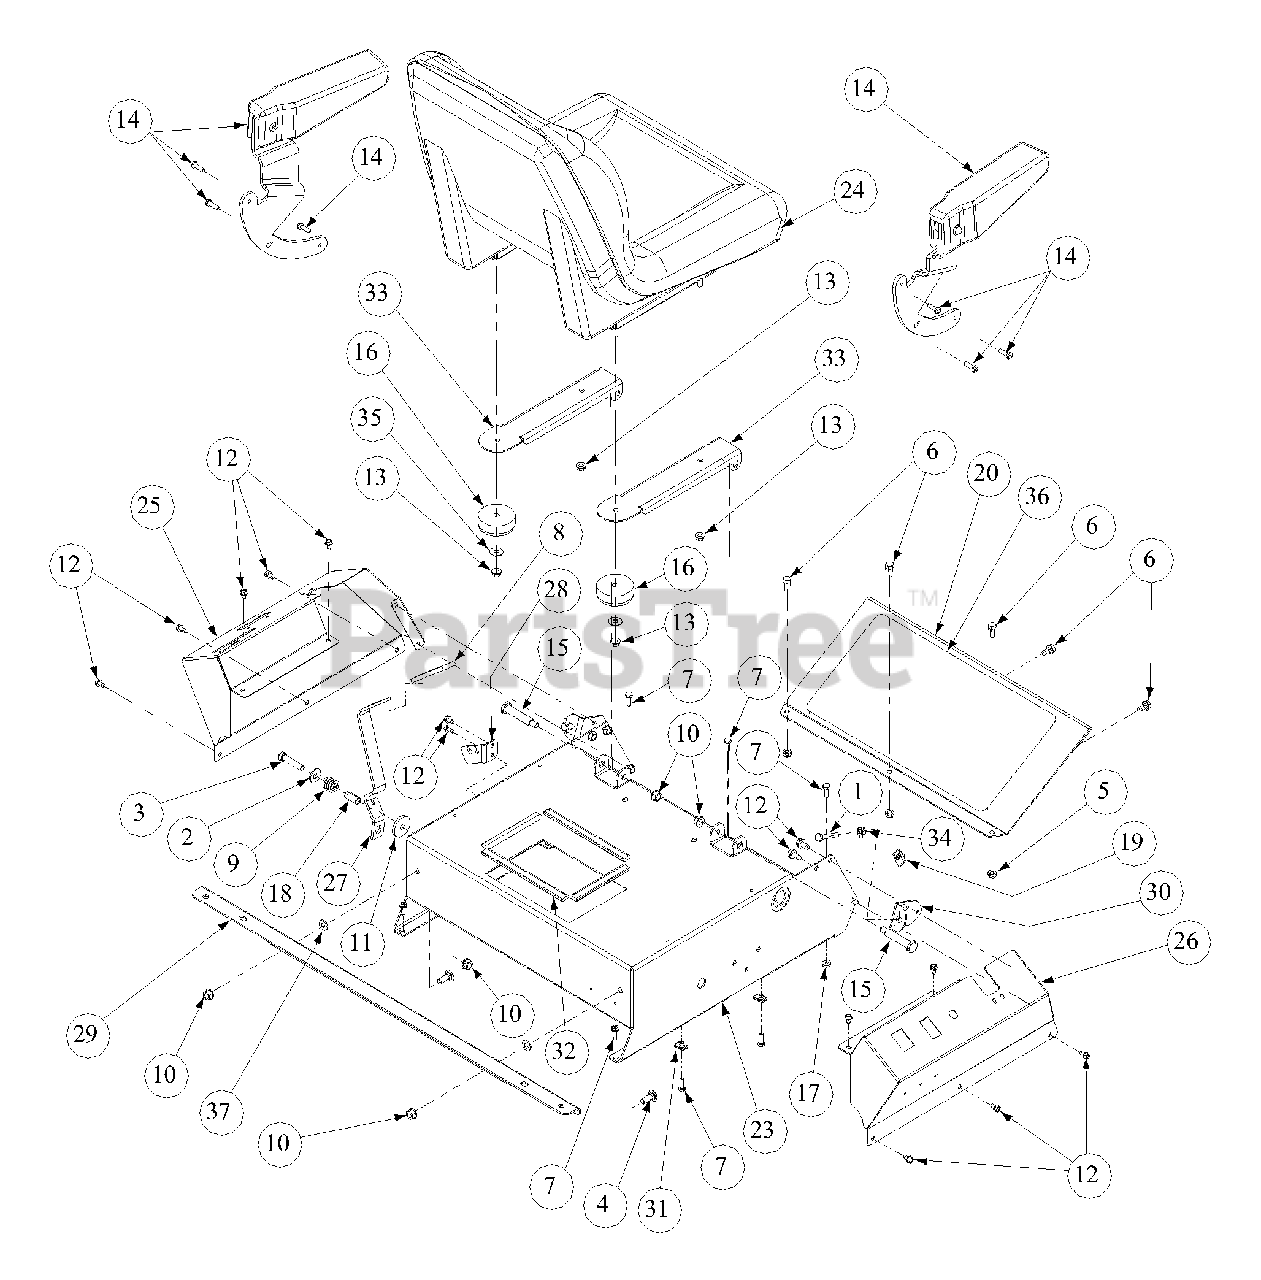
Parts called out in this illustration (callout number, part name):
1	Hex Cap Screw, 5/16-18 x 1-1/2
2	Idler Washer
3	Capscrew, 3/8-16 x 1-3/4
4	Carriage Bolt, 3/8-16
5	Nylock Nut, 5/16-18
6	Self Tapping Screw, 5/16-18 x 3/4
7	Self Tapping Screw, 1/4-20 x .75
8	Parking Brake Grip
9	Spring, .85 OD x 1 Lg
10	Hex Nut, 3/8-16 Flange Lock
11	Flat Washer, 1.25 x .411 x .100
12	Screw, 1/4-20 x 1/2
13	Hex Nut, 5/16-18 Flange Lock
14	Kit, Armrest (Available through Whole goods)
15	Shoulder Screw, 3/8-16, .5 x 2.345
16	Groment, 2.5 OD x 1.0 Lg
17	Hex Nut, 1/4-20 Flange Lock
18	Spacer, .375 x .50 x 1.02
19	U-Nut, 5/16-18
20	Foot Rest Bracket
23	Control Housing Weldment
24	Seat Adjust
25	Left Hand Control Console
26	Right Hand Control Console
27	Parking Brake Lever
28	Brake Cable Bracket
29	Front Tank Mounting Bracket
30	Lapbar Stop Bracket
31	U-Nut, 1/4-20
32	Battery Edge Trim
33	Seat Mounting Bracket
34	Hex Nut, 5/16-18
35	Washer, .325 x .930 x .045
36	Abrasive Foot Pad
37	Flat Washer, .406 ID x 1.0 OD x .105
